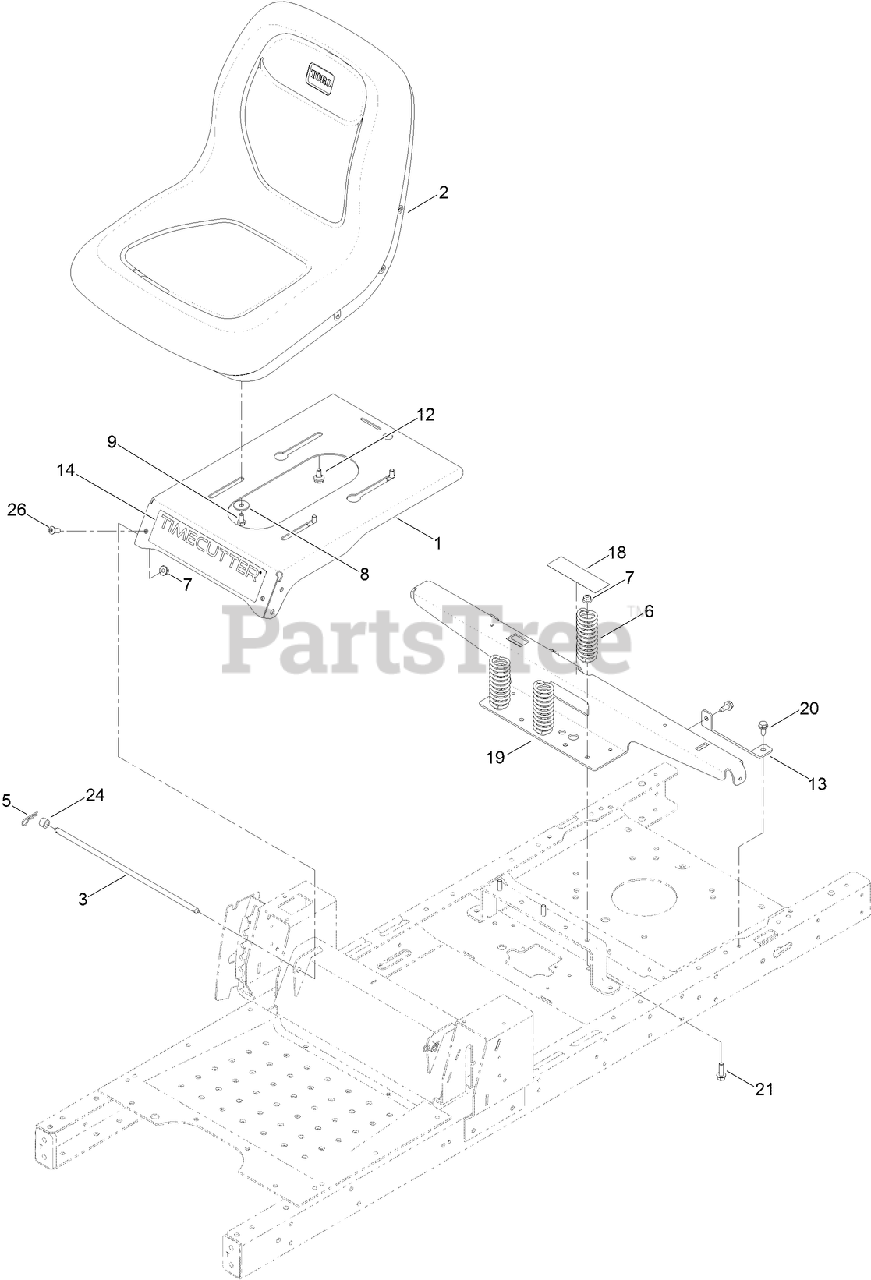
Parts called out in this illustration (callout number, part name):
2	SEAT-18 INCH
3	ROD-STOP
5	PIN-COTTER
6	SPRING-COMPRESSION
7	NUT-HF, NI
8	WASHER-PIVOT
9	SCREW-HH
12	BOLT-SHOULDER,HFH
13	SUPPORT-TANK, REAR
14	DECAL-TIMECUTTER
18	DECAL-SERVICE, CE
19	SUPPORT-POD, WIDE
20	SCREW-HWHTF
21	SCREW-HHF
24	BUSHING-LEVER, LIFT
26	SCREW-HSBH
